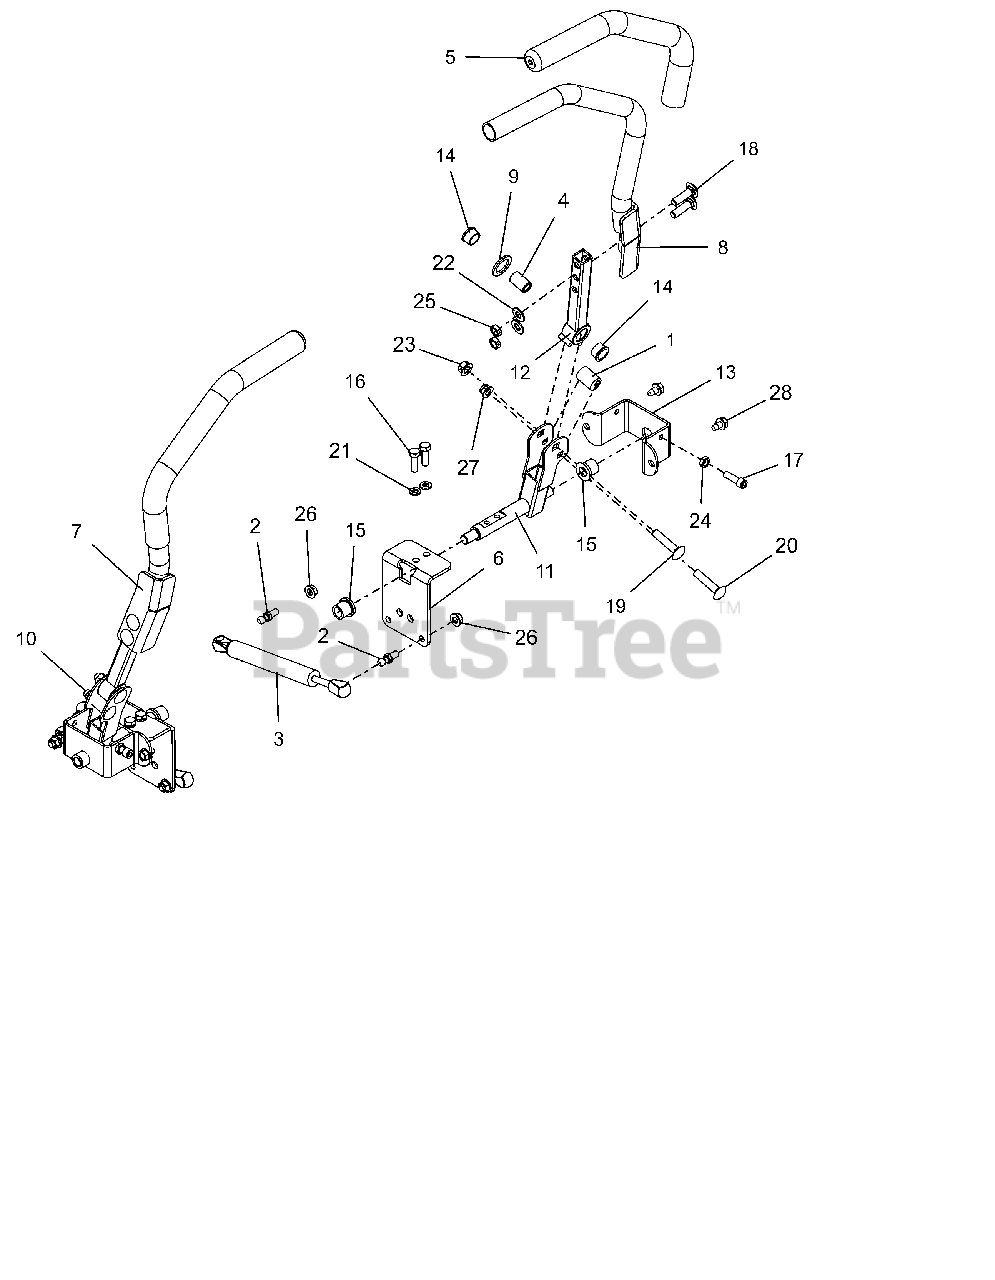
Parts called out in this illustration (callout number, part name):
1	BSHG,ECCEN .328X.750X1.01 PM
2	STUD- BALL
3	DAMPER, STABILUS
4	SPACER, .375X.625X.970 (PM)
5	GRIP, HANDLEBAR 15" FOAM
6	BRKT, STEEERING
7	WLDMT, STEERING HANDLE RH
8	WLDMT, STEERING HANDLE LH
9	WASHER, FRICTION .875X1.25X.10
10	WLDMT,STEERING ARM LOWER RIGHT
11	WLDMT,STEERING ARM LOWER LEFT
12	WLDMT, UPPER CONTROL ARM
13	BRKT, STEERING
14	BSHG-FLG, .625X.75X.450X.875
15	BSHG-FLG .515X.750X.745X1.00NY
16	BLT-HEX .31-18X1.00 GR8 YWZC
17	SCR, SKH .312-18X1.00 G8 ZC120
18	BLT,RHSSN-.375X1.25 G5 RIE5230
19	BLT,RHSSN-.375X1.75 G5 RIE5230
20	BLT,RHSSN-.375X1.75 G5 RIE5230
21	@WSHR-LK .31X.078 REG YWZC
22	@WSHR-FL-STL.406X.812X.065 YWZ
23	NUT-LK-CTR-FLG .38-16 YWZC
24	NUT- JAM .312-18 YWZC
25	@NUT-LK-CTR-JAM .375-16 YWZC
26	@NUT-LK-TOP-FLG .31-18 YWZC
27	@NUT-LK-NYL-FLG .31-18 YWZC
28	@SCR-TAP .31-18X.50 HWH TR YWZ
